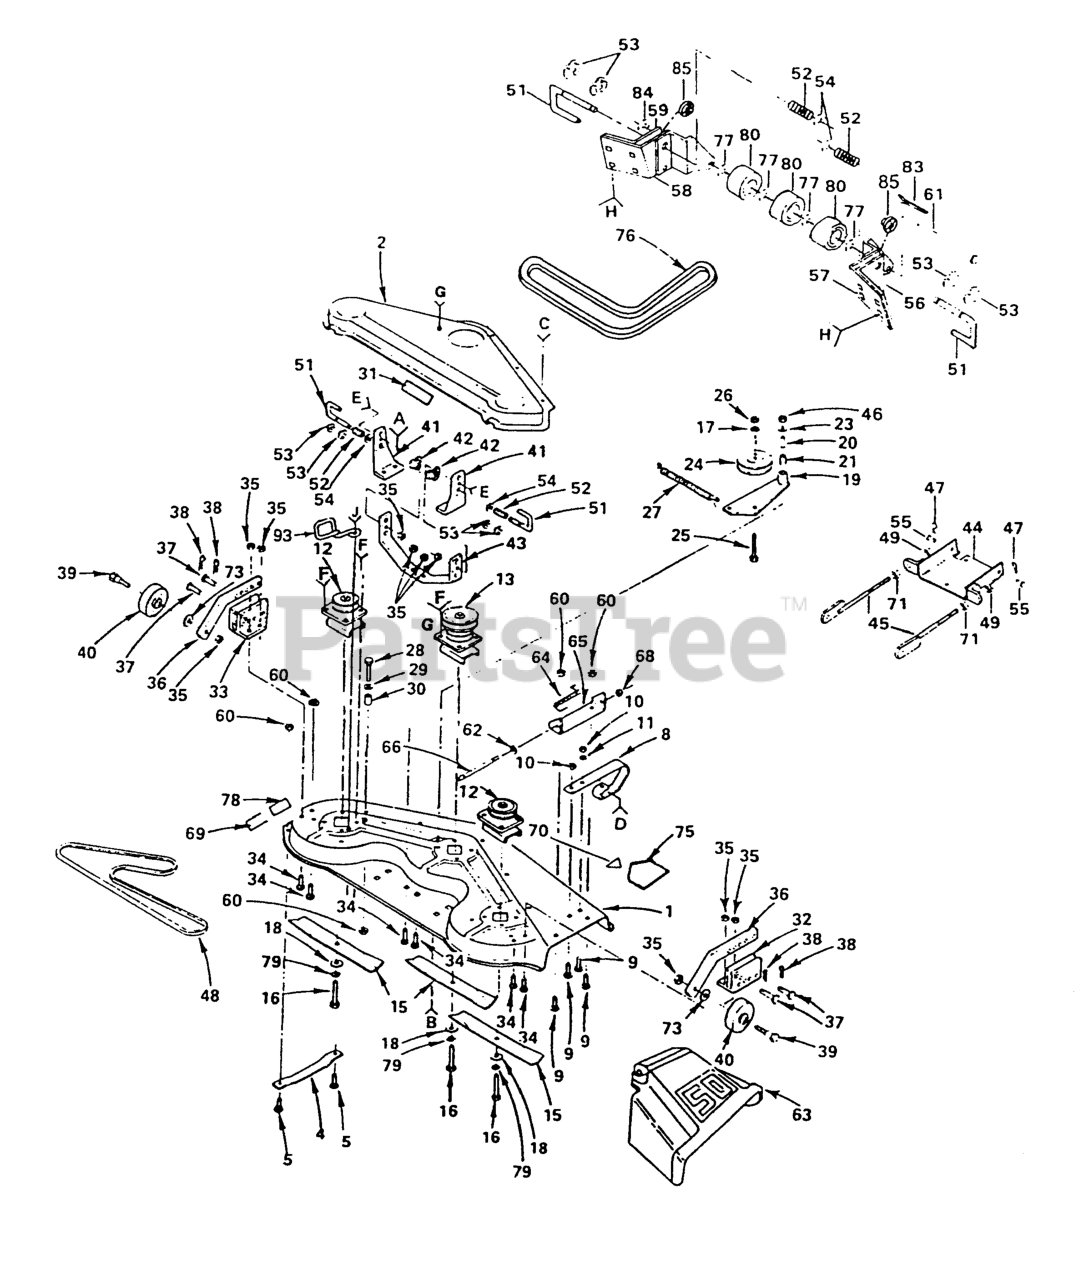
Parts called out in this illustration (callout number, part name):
1	HOUSING
2	CVR DRIVE DECK
4	RUNNER-LH M
5	BOLT.CARR.5/16-18X5/8.SHORT
8	RUNNER T
9	RP BOLT 5/16-18 X3/4 ZN/YEL GR
11	WASHER
12	JACKSHAFT YT
13	JACKSHAFT.PRIMARY
15	BLADE.50".STANDARD.LIFT
16	BOLT.3/8-24X1-1/2
17	WASHER, LOCK 3/8
18	WASHER
19	ARM ASSY GT
20	BEARING ASSY M
21	BEARING ASSY M
23	Washer 11/32 x 1-1/8 x 16 Ga.
24	IDLER-FLAT T
25	BOLT
26	NUT.HEX.3/8-16UNC
28	BOLT.5/16-18X1-1/4 FULL.THREAD
29	WASHER M
30	SPACER SPLIT LT
31	DECAL V BELT
32	GUAGE WHL BRKT GT
33	GAUGE WHL BRKT GT
34	Bolt, Carriage 3/8 - 16 x 3/4
36	GUAGE WHL BAR GT
37	CLEVIS PIN T
38	RETAINER-SPRNG RB
39	BOLT M
40	WHEEL.GAUGE.BLK.4.93
41	SUSP BRKT GT
43	SUSP BRACE GT
45	BRACKET NLA
46	JAM NUT TI
47	SPRING RETAINER
49	NUT LTV
51	RELEASE PIN GT
52	SPRING.COMPRESSION
54	WASHER GT
55	CLEVIS PIN GT
60	LOCKNUT
61	PIVOT PIN T
62	Washer 11/32 x 5/8 x 16 Ga.
63	SHIELD.DEFLECTOR.MOWER.50"BLK.
64	DEFLECTOR SPRG T
65	BRACKET T
66	ROD-HINGE T
68	NUT PUSH M
70	Decal, Safety Standard
71	NUT.HEX.3/8-16UNC
73	Washer 17/32 x 15/16 x 12 Ga
75	DECAL WARNING
76	BELT-V.93.5.MOWER
77	WASHER T
78	DECAL-INST YT
79	LOCKWASHER
83	COTTER PIN
84	WASHER
93	BELT RETIANER
